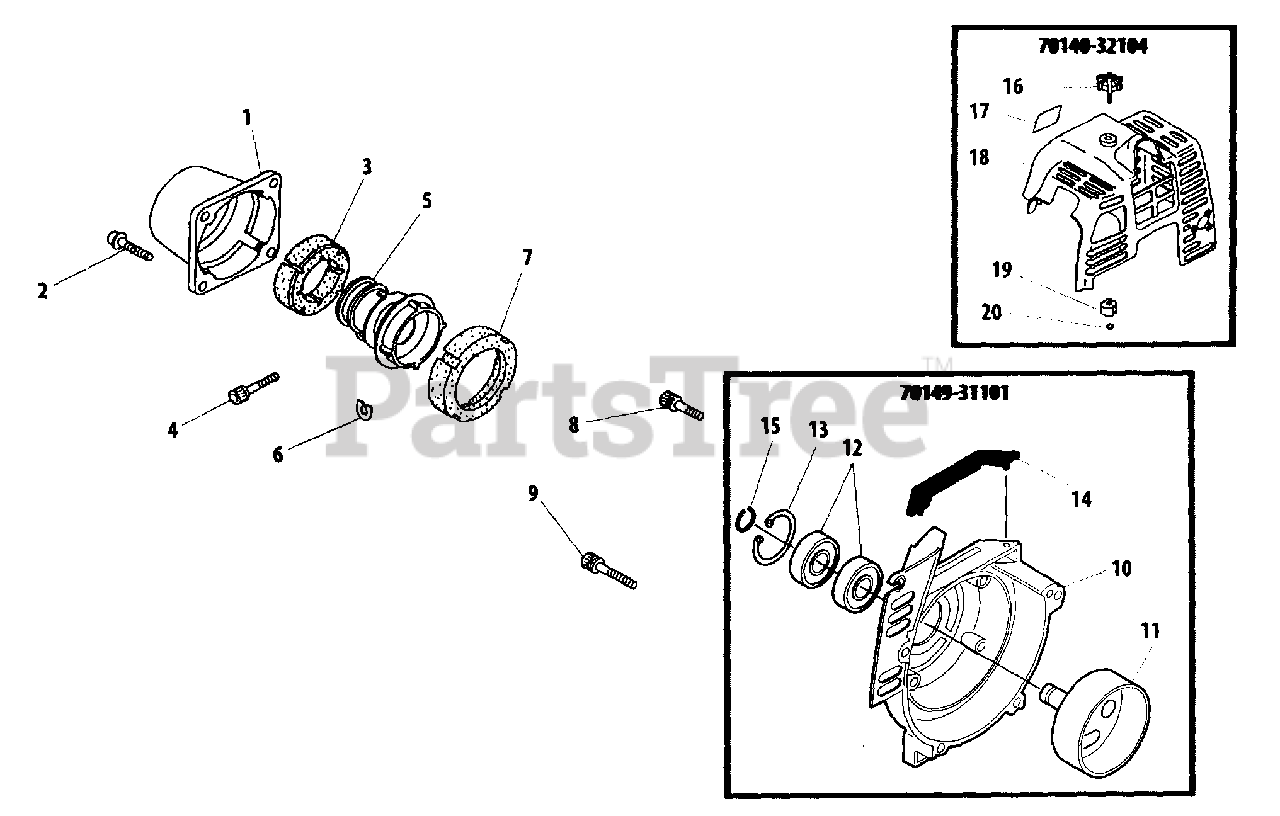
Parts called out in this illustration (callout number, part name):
1	CAP
2	SCREW - 5X16
3	CUSHION - FRONT
4	SCREW - 5X25
5	CLAMP, MAIN PIPE
6	SHIM
7	CUSHION - REAR
8	SCREW - 5X16
9	SCREW - 5X35
10	CASE, FAN
11	DRUM, CLUTCH
12	BEARING, BALL - 6000
13	RING, RETAINING - 26
14	CUSHION
15	RING, RETAINING
16	THUMBSCREW
17	LABEL
18	COVER, ENGINE
19	INSULATOR
20	CLIP
70140-32104	ENGINE COVER KIT - RED
70149-31101	FAN CASE ASSY
